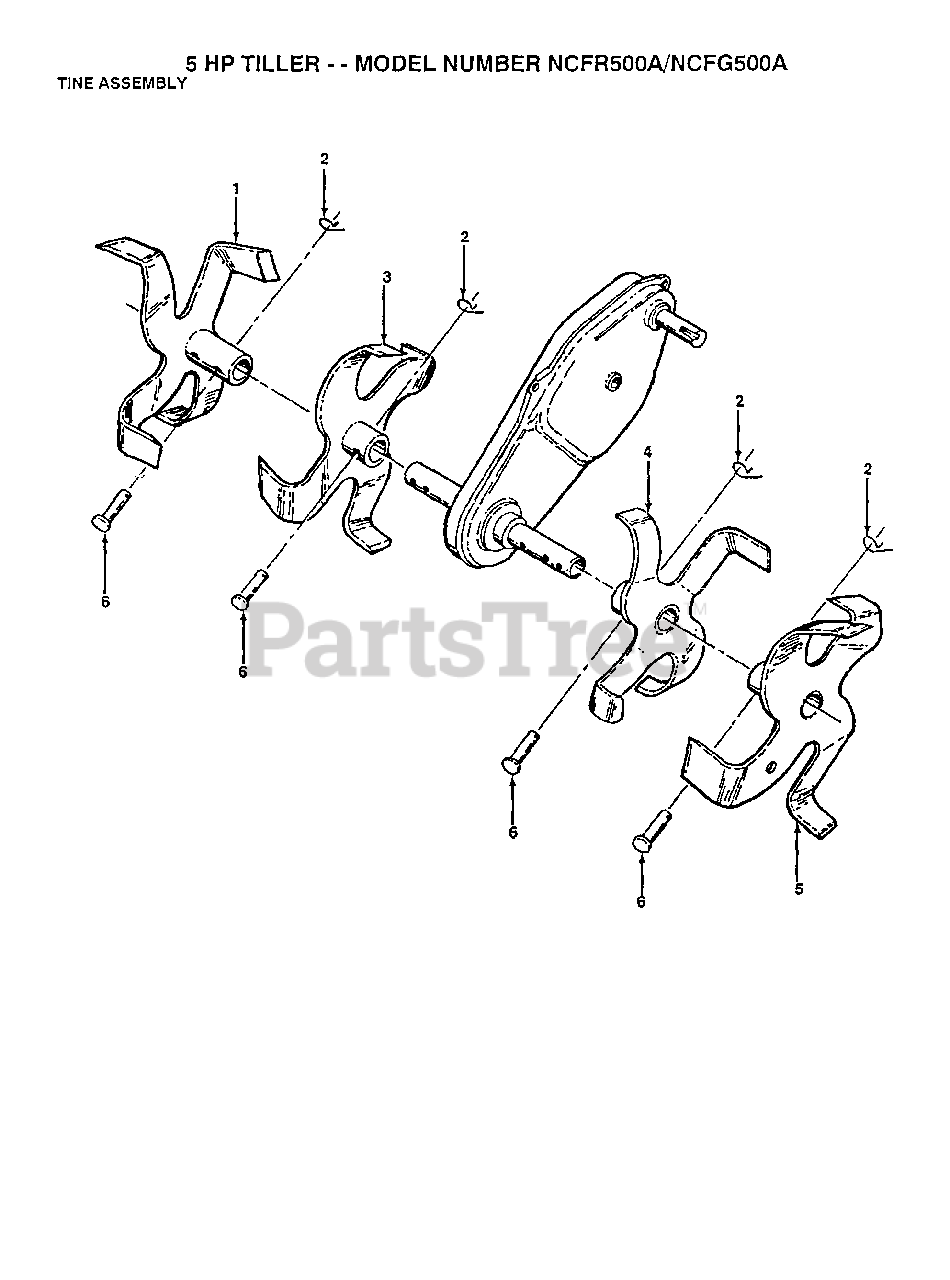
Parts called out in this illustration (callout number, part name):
1	TINE WELDMENT TI
2	RETAINER.SPRING
3	TINE TI
4	TINE TI
5	TINE WELDMENT TI
6	RIVET.PAN HD.1.75
